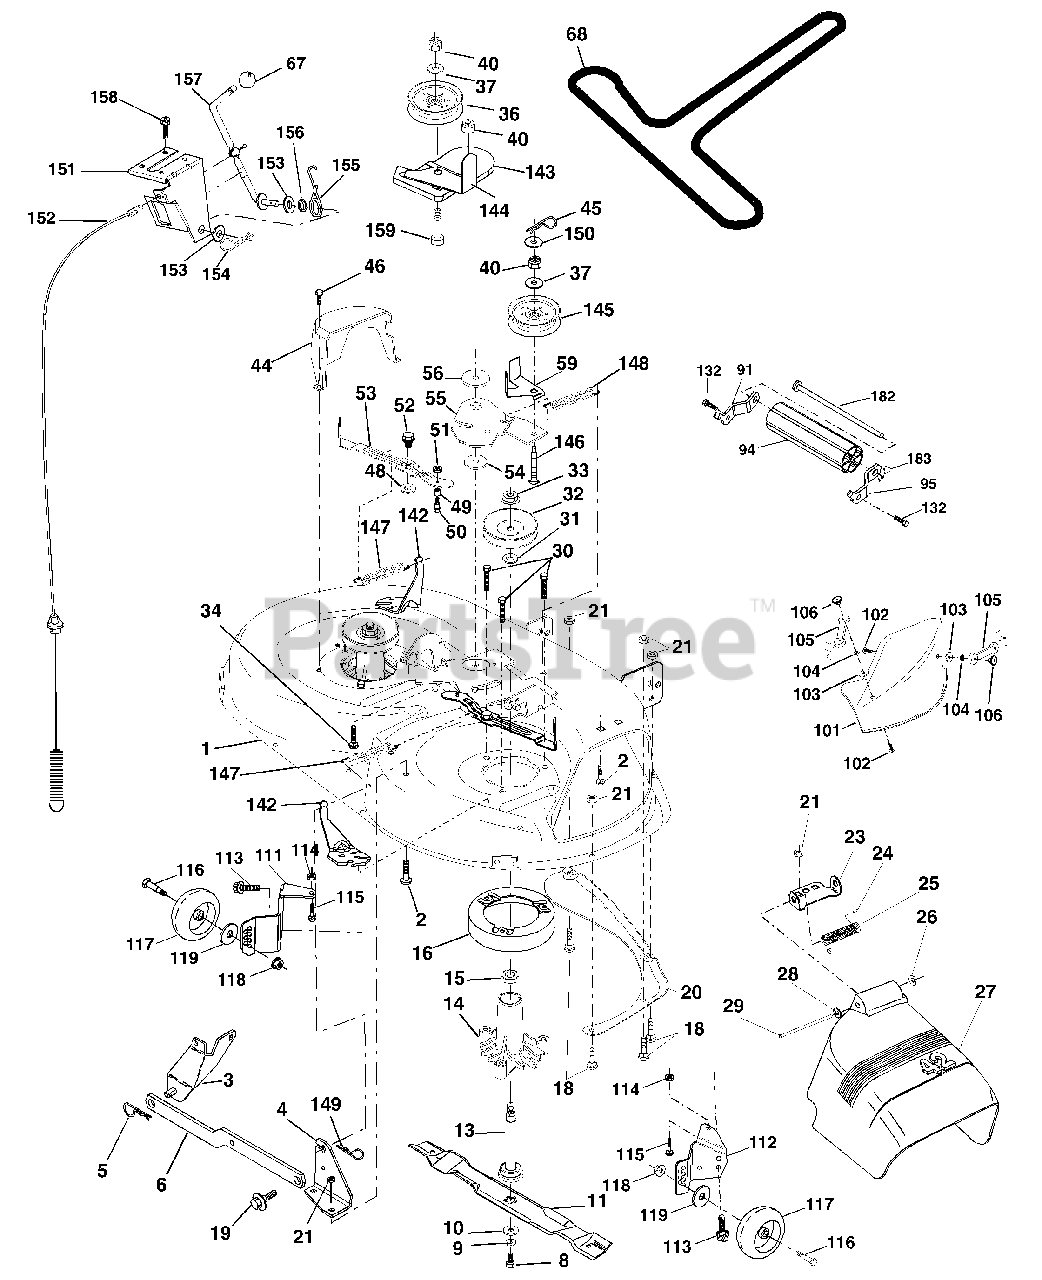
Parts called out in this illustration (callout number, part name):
1	Mower Deck Assembly, 42"
2	Bolt
3	Bracket Asm Fr. Sway Bar 3/42
4	Bracket Asm Deck 42" Sway Bar
5	Retainer Spring
6	Bar Sway Deck
8	Bolt 3/8-24 x 25 Gr. 8 patched
9	Washer, Lock
10	Washer, Hardened
11	Blade, Mulching 42" Std
11	Blade Mower 42" Hi-Lift Std
13	Shaft Assembly, Mandrel, Vented
14	Housing, Mandrel, Vented
15	Bearing, Ball, Mandrel
16	Stripper, Mower Deck
18	Bolt, Carriage 5/16-18 x 5/8
19	Bolt, Shoulder
20	Baffle, Vortex
21	Nut
23	Bracket, Deflector Mower 42"
24	Cap, Sleeve 80 x 112 Blk Mower
25	Spring, Torsion, Deflector 2 52
26	Nut, Push Phos & Oil
27	Shield, Deflector 42" Blk
28	Washer 11/32 x 5/8 x 16 Ga.
29	Rod, Hinge 42" 6 75 W/G
30	Screw Thdrol
31	Washer, Spacer Mower Vented
32	Pulley, Mandrel
33	Nut, Toplock 9/16
34	Bolt
36	Pulley, Idler, Flat
37	Washer 13/32 x 13/16 x 16 Ga.
40	Nut
44	Guard, Mandrel, LH
45	Retainer
46	Screw, Thdrol 1/4-20 x 5/8 T
48	Washer, Hardened
49	Roller Assembly, Cam Follower
50	Bolt, Shoulder #10-24 Grade 5
51	Locknut
52	Bolt, Shoulder 5/16-18 Unc
53	Arm Assembly, Pad, Brake
54	Washer, Hardened
55	Arm, Idler
56	Spacer, Retainer
59	Guard TUV Idler
67	Knob Round
68	V-Belt, 42" Mower
91	Bracket Roller Nose Lh
94	Roller Nose 38 & 42
95	Bracket Roller Nose Rh
101	Mulcher Cover
102	Screw Pan Hd Phillips 10-24 x 5/8
103	Washer, Flat
104	Washer, Lock
105	Latch Assembly
106	Nut, Weld
111	Bracket, Ga., Wheel LH
112	Bracket, Ga., Wheel RH
113	Screw 3/8-16 x .625
114	Nut, Keps 5/16 - 18 Unc
115	Bolt, Carriage 5/16-18 x 5/8
116	Bolt, Shoulder
117	Wheel, Ga.
118	Nut Centerlock 3/8-16
119	Washer 3/8 x 7/8 x 14 Ga.
121	Bracket, Extruded
132	Screw 3/8-16 x .75
142	Arm Spring Brake Mower
143	Bracket Arm Idler 42"
144	Keeper Belt 42" Clutch Cable
145	Pulley Idler Flat
146	Bolt Carriage Idler
147	Spring Extension
148	Spring Return Idler
149	Retainer Spring Yellow
150	Washer 9/32 x 3/4 x 16 Ga.
151	Bracket Clutch Cable
152	Clutch Cable 42"
153	Washer Flat 3/8" Type B
154	Spring Retainer
155	Spring Retention LVR CLTCH CAB
156	Spacer Clutch Cable
157	Rod Clutch Cable 3/8"
158	Screw Hex Thd Cut 1/4-20 x 1/2
159	Bolt Rdhd Sqn 3/8-16 Unc x 1-3/4
182	Rod Roller Nose
183	Retainer Spring
